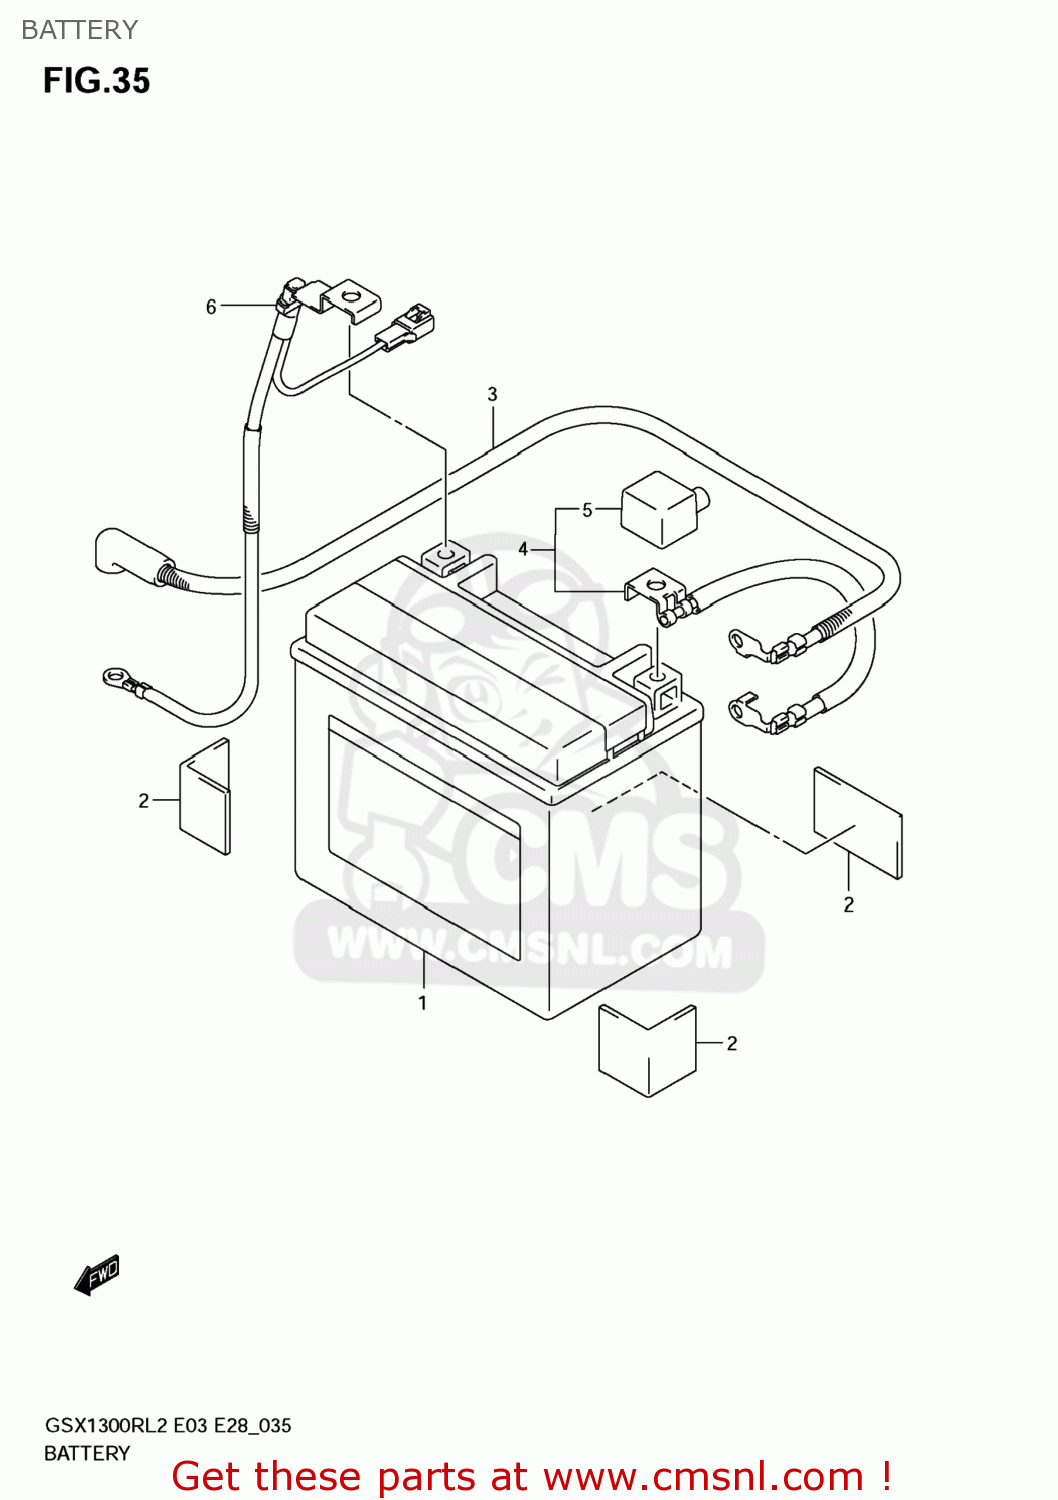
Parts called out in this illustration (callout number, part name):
1	BATTERY ASSY(YTX12-BS,12V10AH)
2	CUSHION(30X50X3)
3	WIRE,STARTER MOTOR LEAD
4	WIRE,BATTERY PLUS LEAD
5	CAP,BATTERY PLUS
6	WIRE,BATTERY MINUS LEAD
